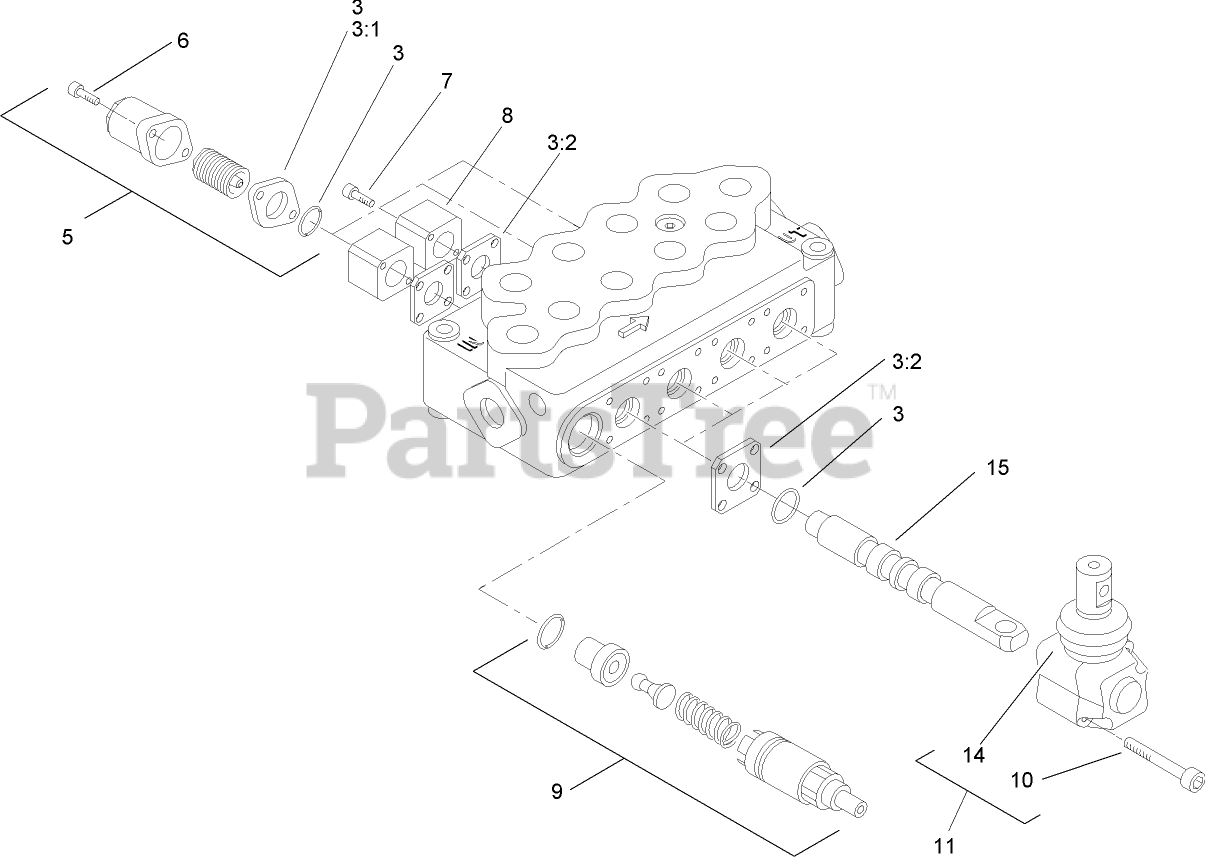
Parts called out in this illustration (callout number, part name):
3	SEAL KIT
3:1	GASKET
3:2	GASKET
5	HIGH FORCE SPRING KIT
5	STANDARD SPRING KIT
6	SCREW-CAP, END
8	BLOCK-MOUNT, SWITCH
9	VALVE-RELIEF
11	OPERATOR ASM
15	SPOOL-VALVE
